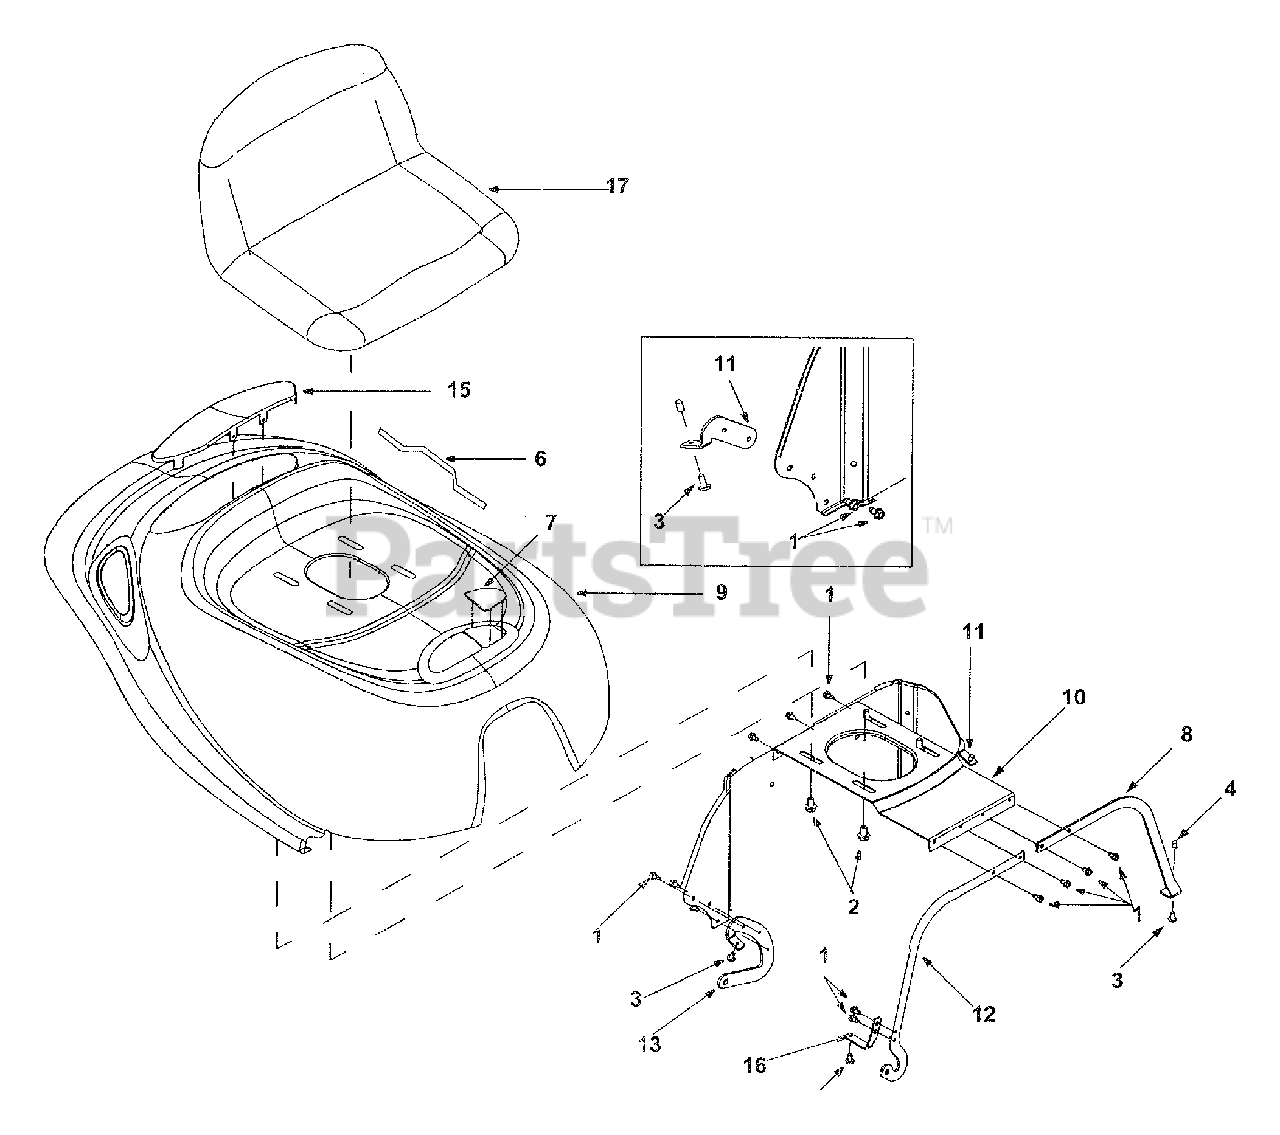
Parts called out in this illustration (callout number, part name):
1	TT Screw 1/4-20 x 0.5
2	TT Screw 3/8-16 x 0.62
3	Torx AB Screw 1/4-14 x 0.625
4	Rod End Grip
6	Trim Strip
7	Grass Bag Lens
8	Bracket Reinforcement: Hood
10	Plate: Hood
11	Hood Bracket
12	Hood Bracket: Reinforcement
17	Seat
